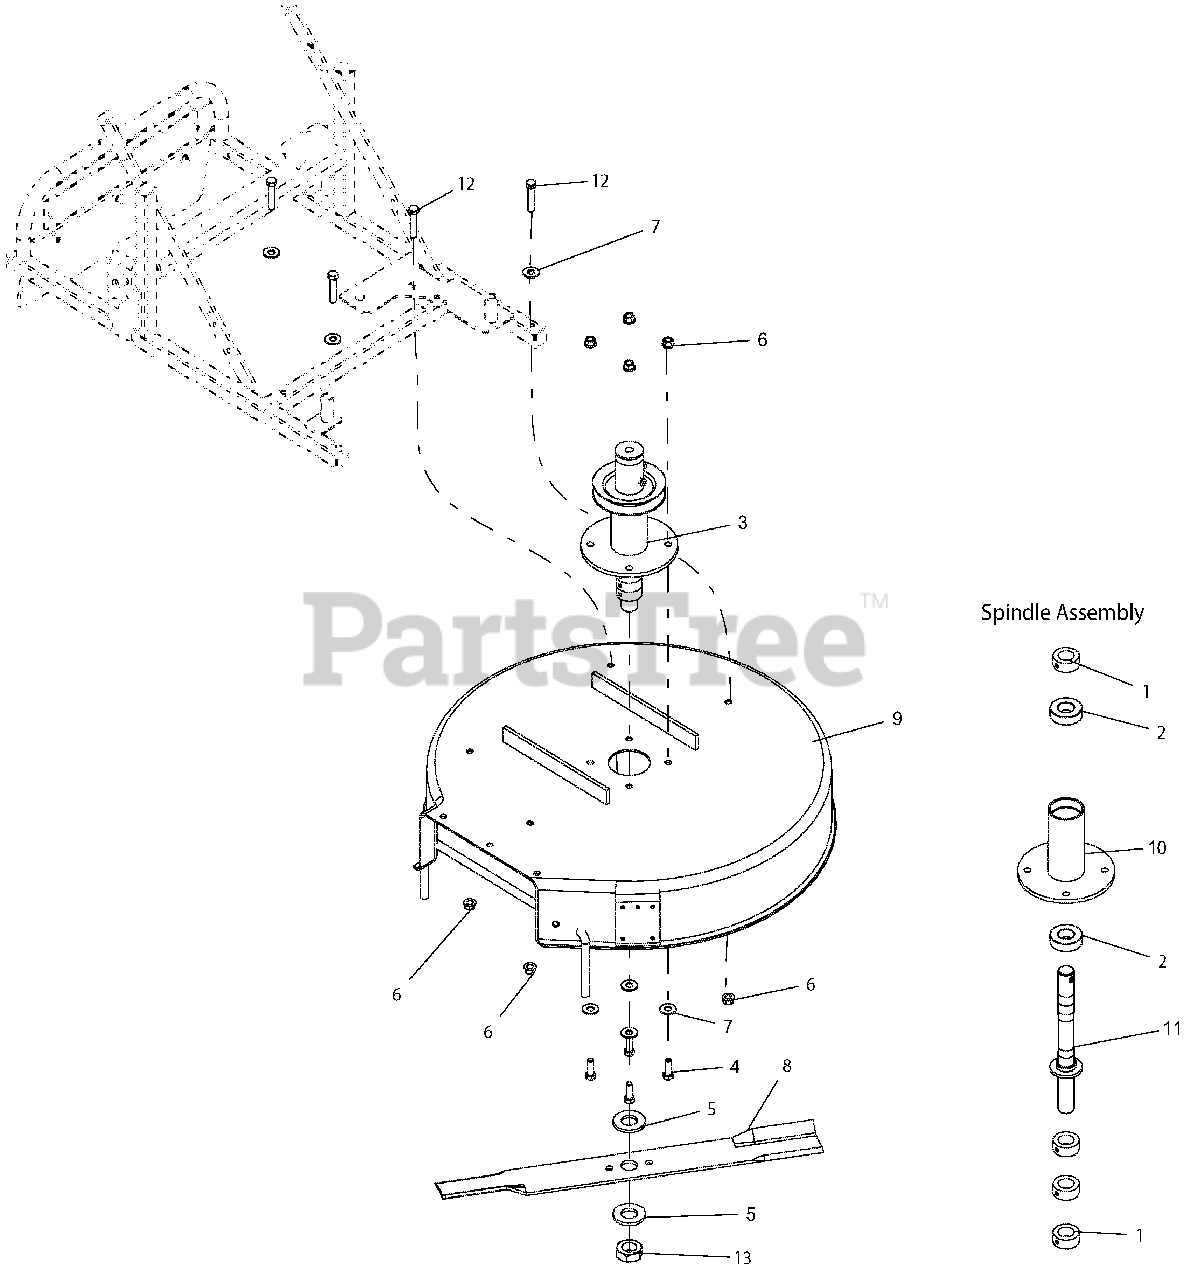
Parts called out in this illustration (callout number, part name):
1	LOCKING COLLAR 1IN
2	BEARING 1.00 ID X 2
3	SPINDLE ASSY, HWM
4	BLT-HEX .38-16X1.00 GR5 YWZC
5	1"USS WASHER HARD NO PLA
6	NUT, LK-TOP-FLG .38-16 YWZC
7	WSHR-FL-STL.438X1.00X.083 YWZC
8	BLADE, KC-24"
9	WMT-DECK, 24" HW MOWER (RED)
10	WMT-SPINDLE, HW MOWER (BLACK)
11	SHAFT, SPINDLE , HWM
12	BLT-HEX .38-16X1.75 GR5 YWZC
13	JAM NUT 1-14 NF
